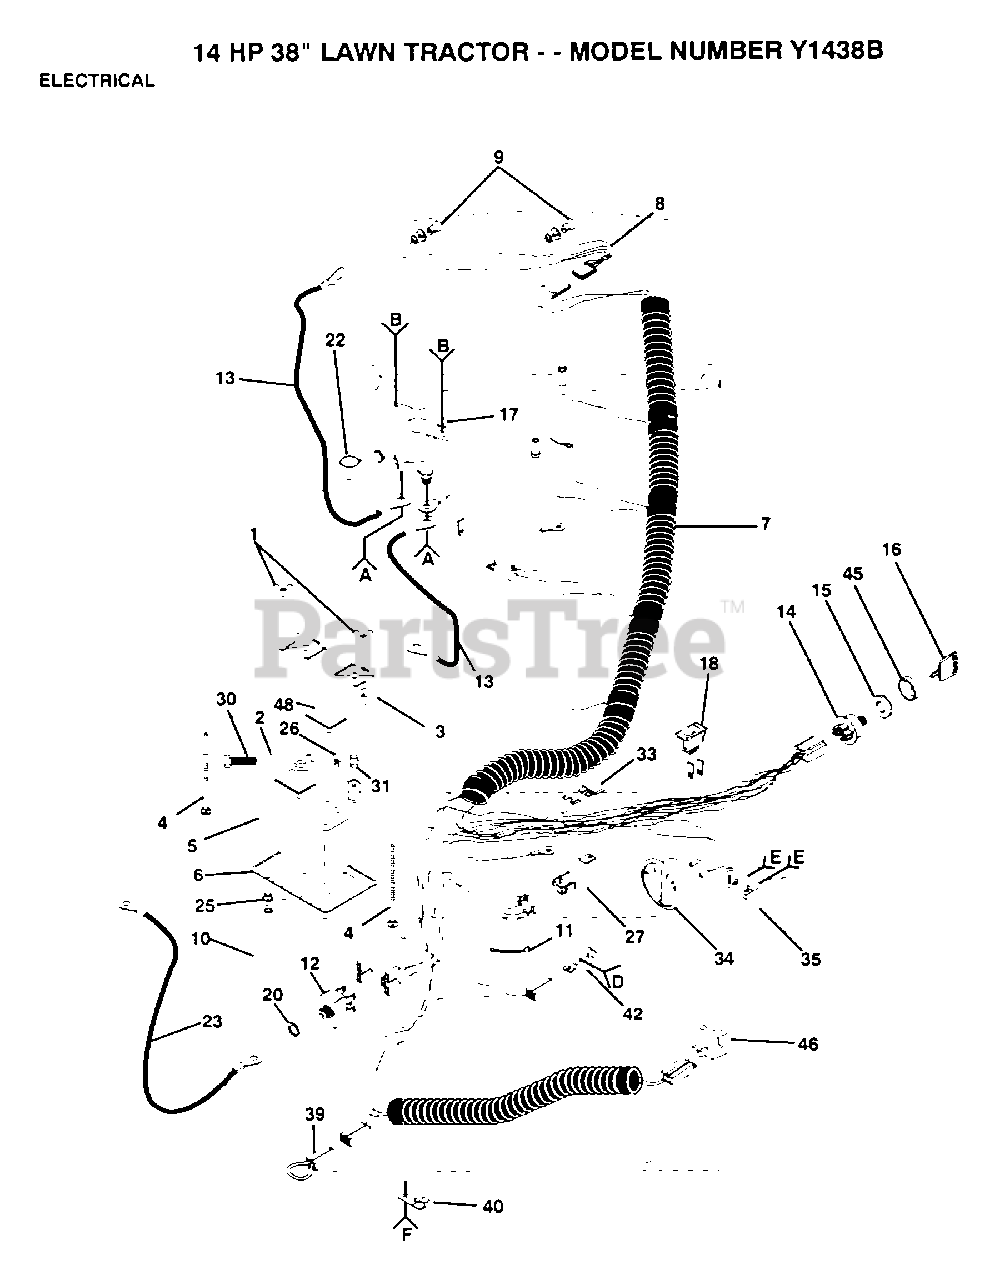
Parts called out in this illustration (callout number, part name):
2	WASHER
4	BOLT
6	"TRAY T, BATTERY"
7	"TRAY T, BATTERY"
9	HEADLAMP BULB
11	WIRE TIE
13	CABLE-BATTERY T
16	KEY
18	SWITCH LT
20	HEX NUT T
23	CABLE T
25	HOSE CLAMP T
26	LOCKWASHER
27	RELAY ASSY T
30	BOLT LT
33	FUSE HYT
34	AMMETER T
40	CLIPT
42	SWITCH-INTER. GT
46	SWITCH SEAT
48	"CAP,BATTERY "
